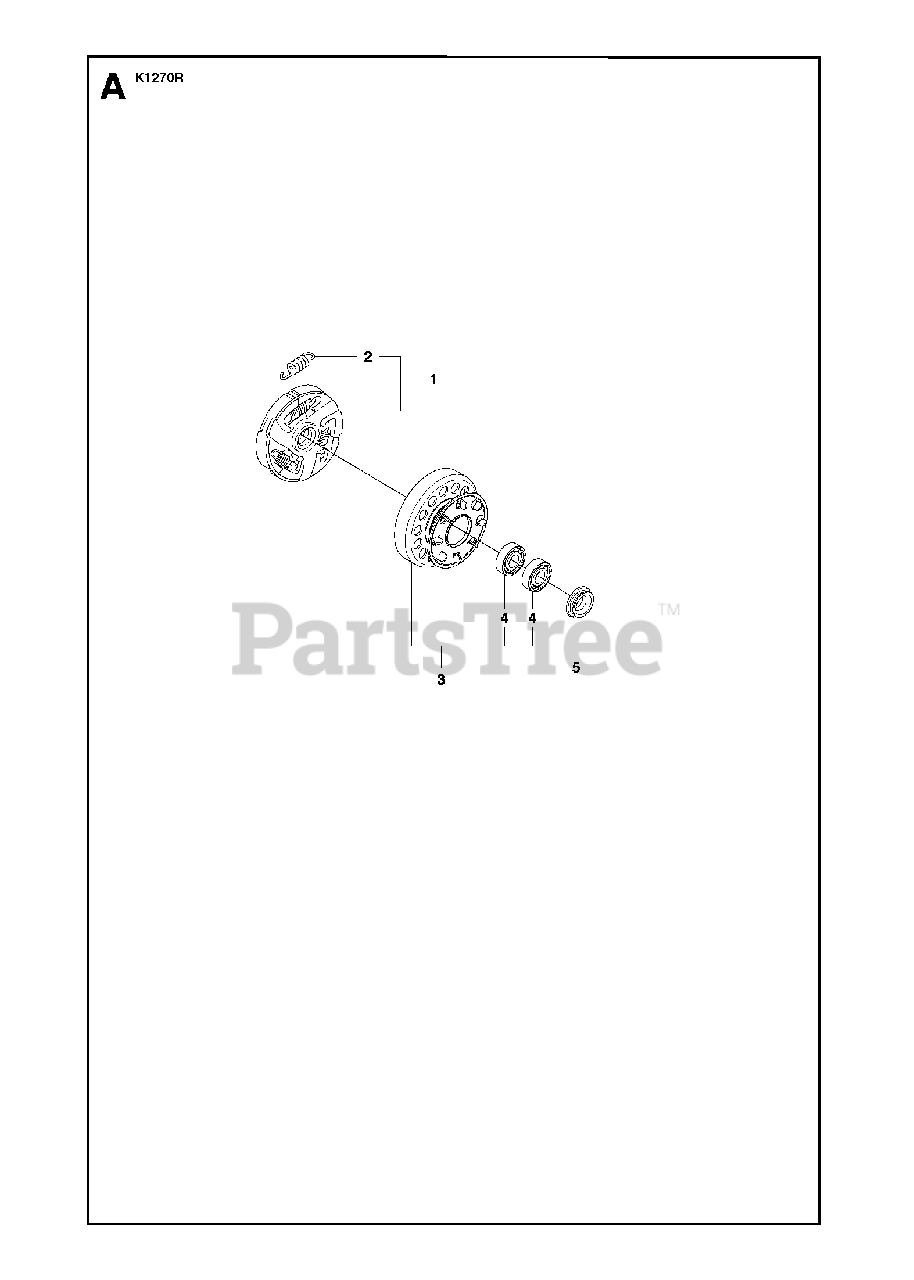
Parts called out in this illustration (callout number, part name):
1	CLUTCH ASSYIncl. 2
2	CLUTCH SPRING
3	DRIVING PULLEY ASSY14"
3	DRIVING PULLEY ASSY16"
4	BALL BEARING
